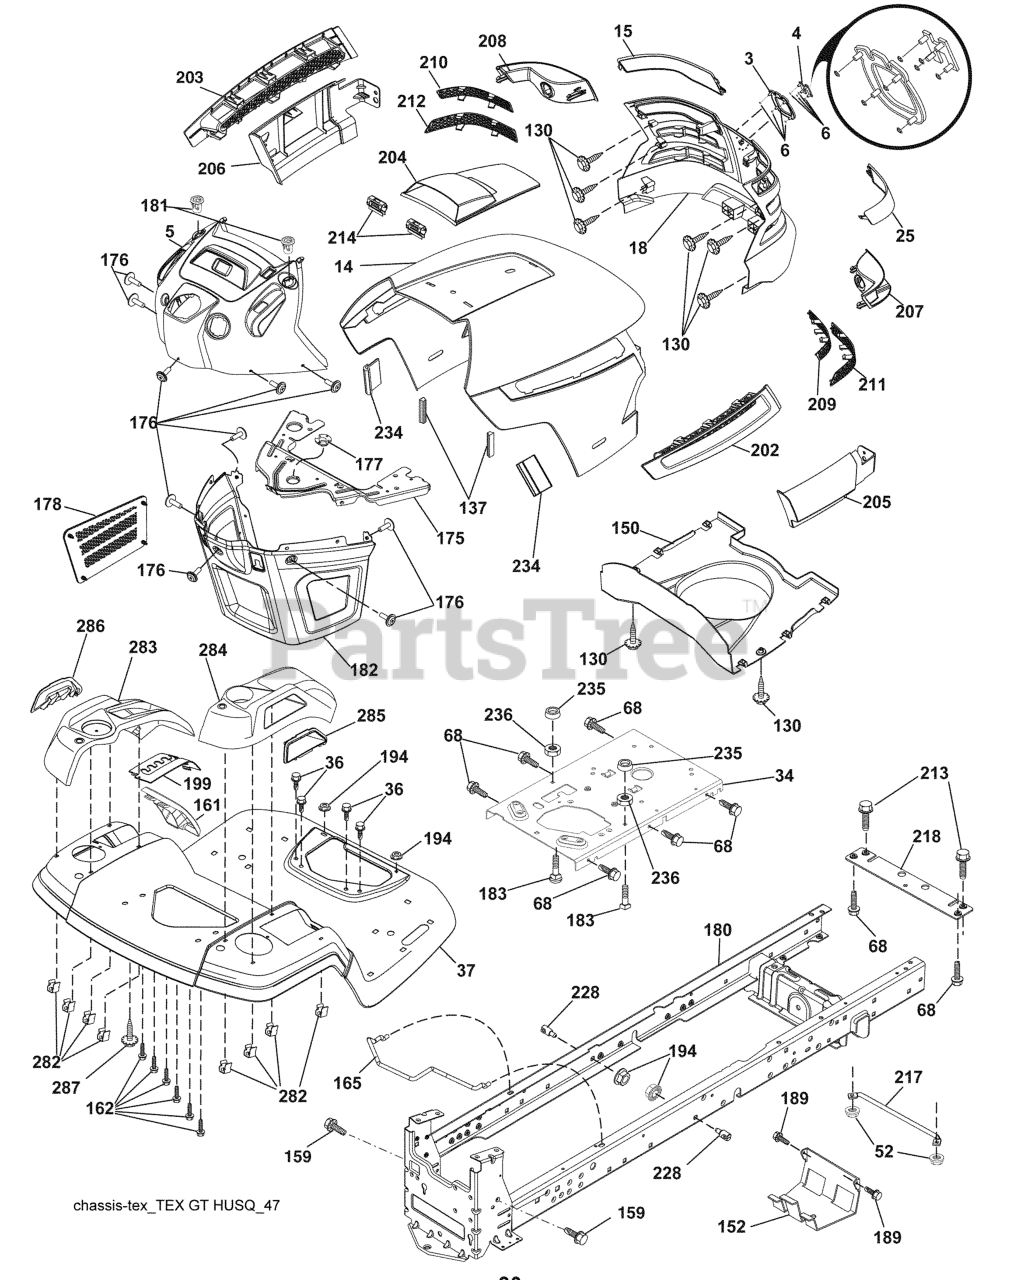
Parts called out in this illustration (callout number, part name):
3	TRIM.HUSQ.TG/CRD.SERVICE
4	RP LOGO
5	DASH ASM.HUSQ.GT.E.RDGA.N/CK.
6	NUT PUSH M
14	HOOD
15	LENS.LH.TEX.GT.HUSQ.CL
18	GRILL.ASM.HUSQ.TG/CRD.W/TRIM
25	LENS.RH.TEX.GT.HUSQ.CL
34	PLATE.ENGINE.WELDED.CHASSIS
36	SCREW 5/16"
37	FENDER.TLT.FS.W/CPH/FW/RSF.ORN
52	LOCKNUT
68	Screw Thdrol 5/16-18 x 1/2
130	SCREW.#10 X 0.750.BOS
137	BUMPER DASH
150	AIR.DUCT.HOOD.TEX.GT.HUSQ
152	SHIELD.BROWNING.W/TEX
159	SCREW, 3/8-16X3/4
161	WINDOW FUEL
162	SCREW.HI-LO.CONSOLE
165	SUPPORT.TANK.REAR.W/TEX
175	PLATE.CROSSMEMBER.HUSQ
176	SCREW.#10-24X5/8.RN.QU
177	BUSHING, STEERING
178	CARGO.ASM.NET.TXGT.W/C
180	CHASSIS
181	BUSHING.MNT.FEND.CRGO.
182	DASH.LOWER.COMMON.12V.ADAPTOR
183	BOLT.5/16-18X1-1/4 FULL.THREAD
189	SCREW
194	NUT LOCK HEX FLANGE 5/16-18
199	PLATE.DECK.LIFT.HUSQ.LT
202	VENT.SIDE.HOOD.HUSQ.RH.GREY
203	VENT.SIDE.HOOD.HUSQ.LH.GRAY
204	HOOD VENT
205	SKIRT.HOOD.SIDE.HUSQ.RH.GREY
206	SKIRT.HOOD.SIDE.HUSQ.LH.GREY
207	BEZEL.RH.TEX.GT.HUSQ
208	BEZEL.LH.TEX.GT.HUSQ
209	INSERT.HEX.GRILL.HUSQ.GREY
210	INSERT.HEX.GRILL.HUSQ.
211	INSERT.HEX.GRILL.HUSQ.
212	INSERT.HEX.GRILL.HUSQ.
213	BOLT
214	CLIP.RETAINER.TINNER.
217	ROD.PIVOT.HOOD
218	X-PIECE.HOOD.STOP.NON/
228	STUD.FASTNER.W/ANTI-ROTATE
234	BUMPER.HOOD.TEX.HUSQVARNA
235	SPACER FENDER
236	NUT.CENTERLOCK.5/16-
282	CLIP.RETAINER.CONSOLE.LT.HUSQ
283	CONSOLE.DECK.LFT.R.SDFL.HUSQLT
284	CONSOLE.CNTRL.
285	CONSOLE INSERT RH
286	CONSOLE.INSRT.LH.HUSQ.LT.BLACK
287	SCREW 1/4X20
